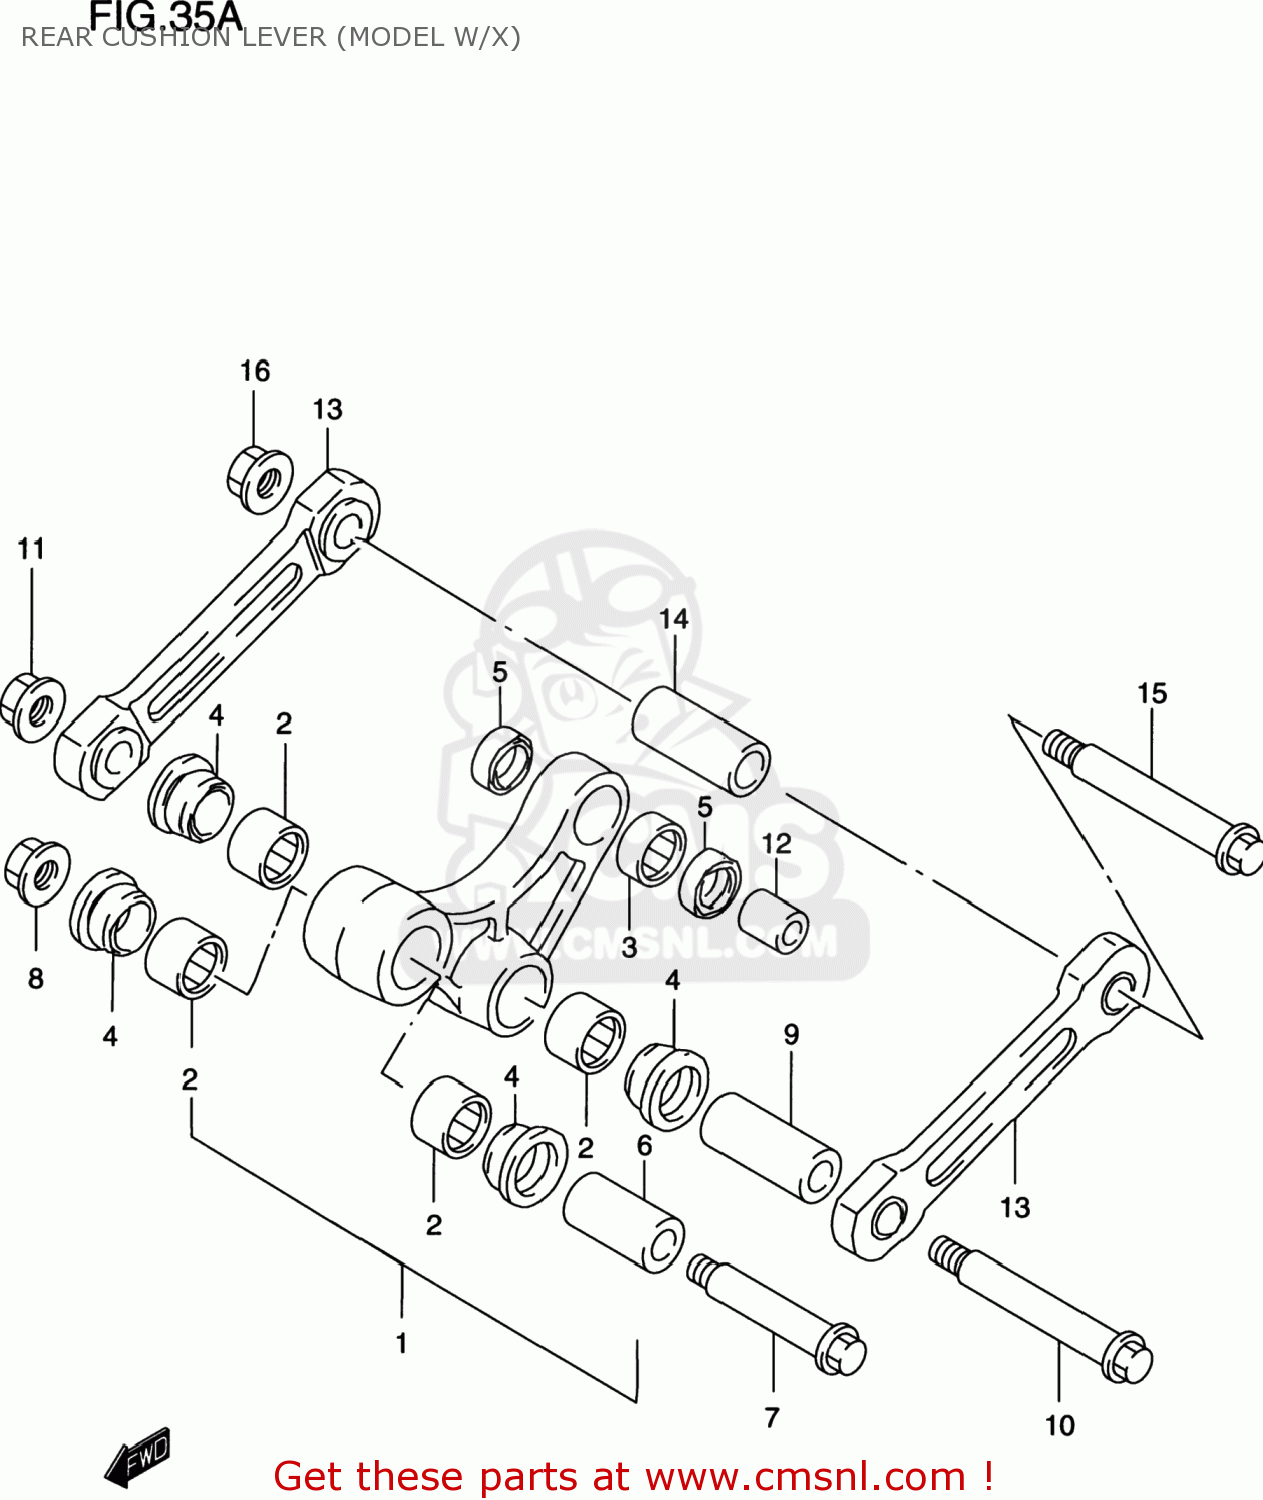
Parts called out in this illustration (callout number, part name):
1	LEVER SET,RR CUSHION
2	BEARING(22X28X16)
3	BEARING(20X26X12)
4	SEAL,SWINGING ARM RR
5	SEAL,OIL(20X26X4.5)
6	SPACER,RR CUSHION LEVER FR
7	BOLT,REAR CUSHION LEVER
8	NUT 12MM
9	SPACER,RR CUSHION
10	BOLT,REAR CUSHION
11	NUT 12MM
12	SPACER,RR CUSHION LEVER RR
13	ROD SET,REAR CUSHION
14	SPACER,RR CUSHION
15	BOLT,REAR CUSHION
16	NUT 12MM
